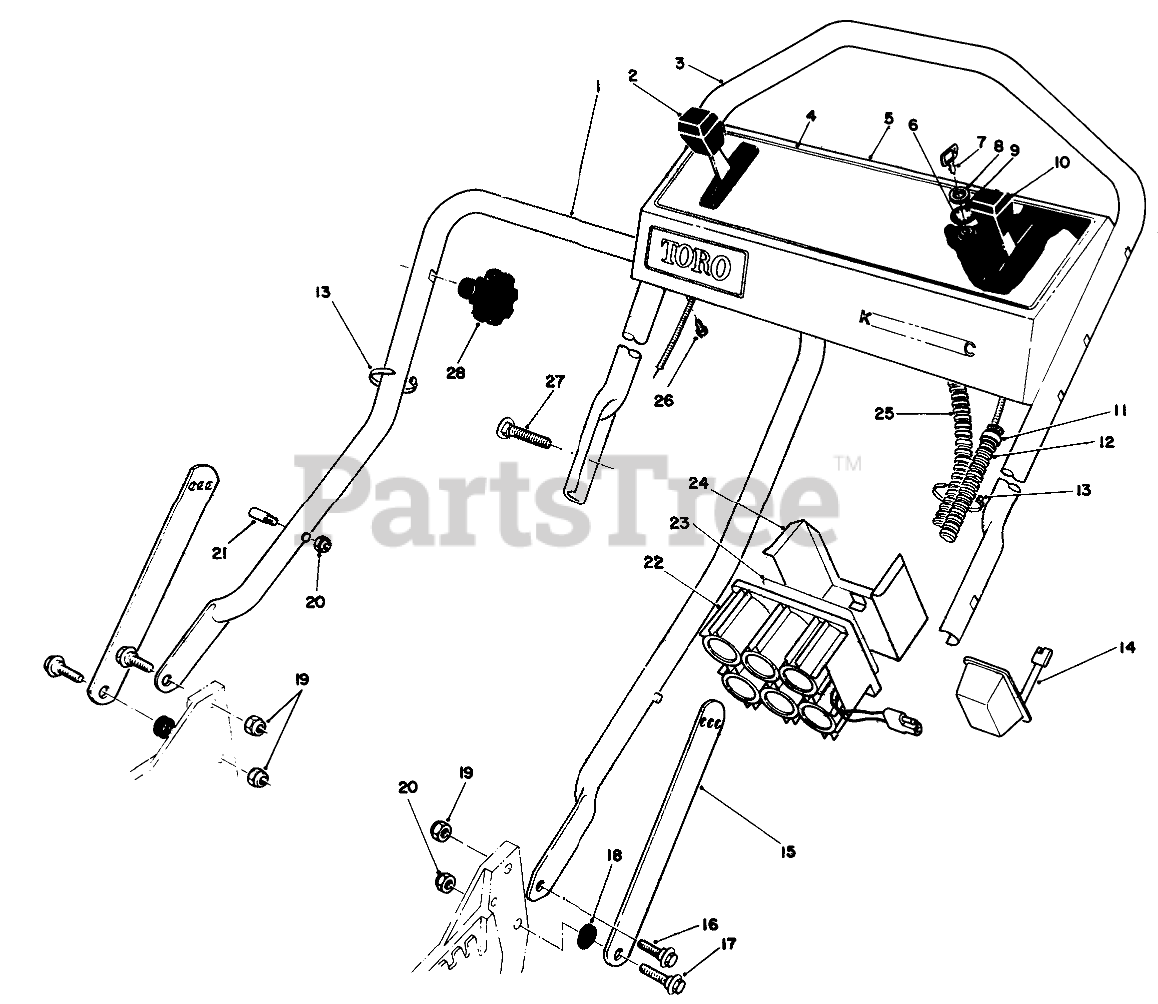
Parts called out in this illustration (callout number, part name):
1	LOWER HANDLE ASM
2	GROUND SPEED CONTROL
3	Handle-Upper
4	Decal-Instruction Panel
5	PANEL W/DECAL
6	Switch-Starter (Incl. Ref. #8-9)
7	KEY-IGNITION
8	NUT-HH
9	WASHER-TOOTH, INTERNAL
10	Control-Throttle (Sheath Lg. 55 1/2 inch, 140.9 cm.)(Wire Lg. 2 1/8 inch, 5.4 cm.)
11	FITTING-RING
12	CONTROL CABLE COVER
13	TIE-CABLE
14	Charger
15	Handle Latch
16	SCREW-SHOULDER
17	SCREW-SHOULDER
18	SPACER
19	NUT-LOCK, NI
20	NUT-LOCK, NI
21	HANDLE PIN
22	BATTERY ASSEMBLY
23	Decal
24	Retainer-Battery
25	WIRE HARNESS
26	SCREW-HWHTF
27	5/16-18 X 2 HNDLE SCREW
